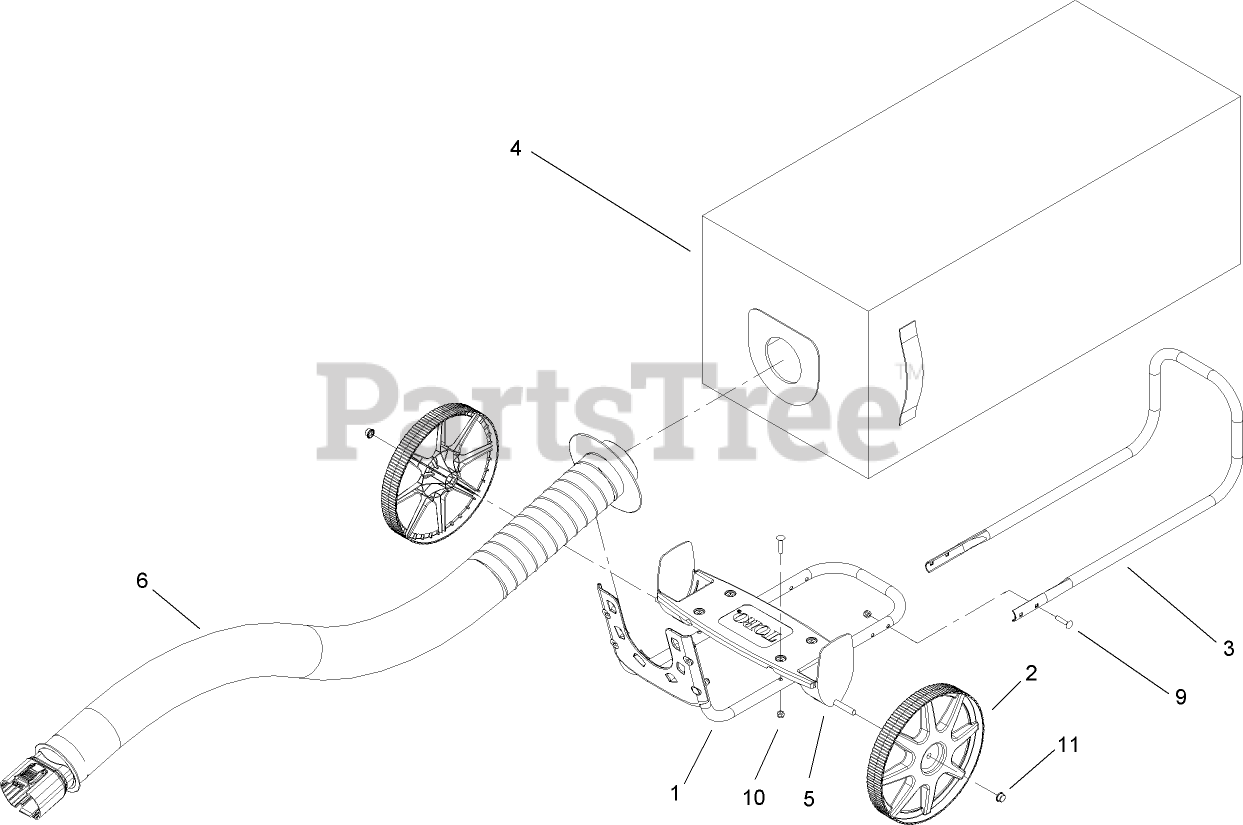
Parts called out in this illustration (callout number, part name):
1	TUBE-FRONT
2	WHEEL-10 INCH
3	TUBE-REAR
4	BAG ASM
5	FENDER ASM
8	Loose Parts Package
9	SCREW-CARRIAGE
10	NUT-LOCK, NI
11	NUT-PUSH
